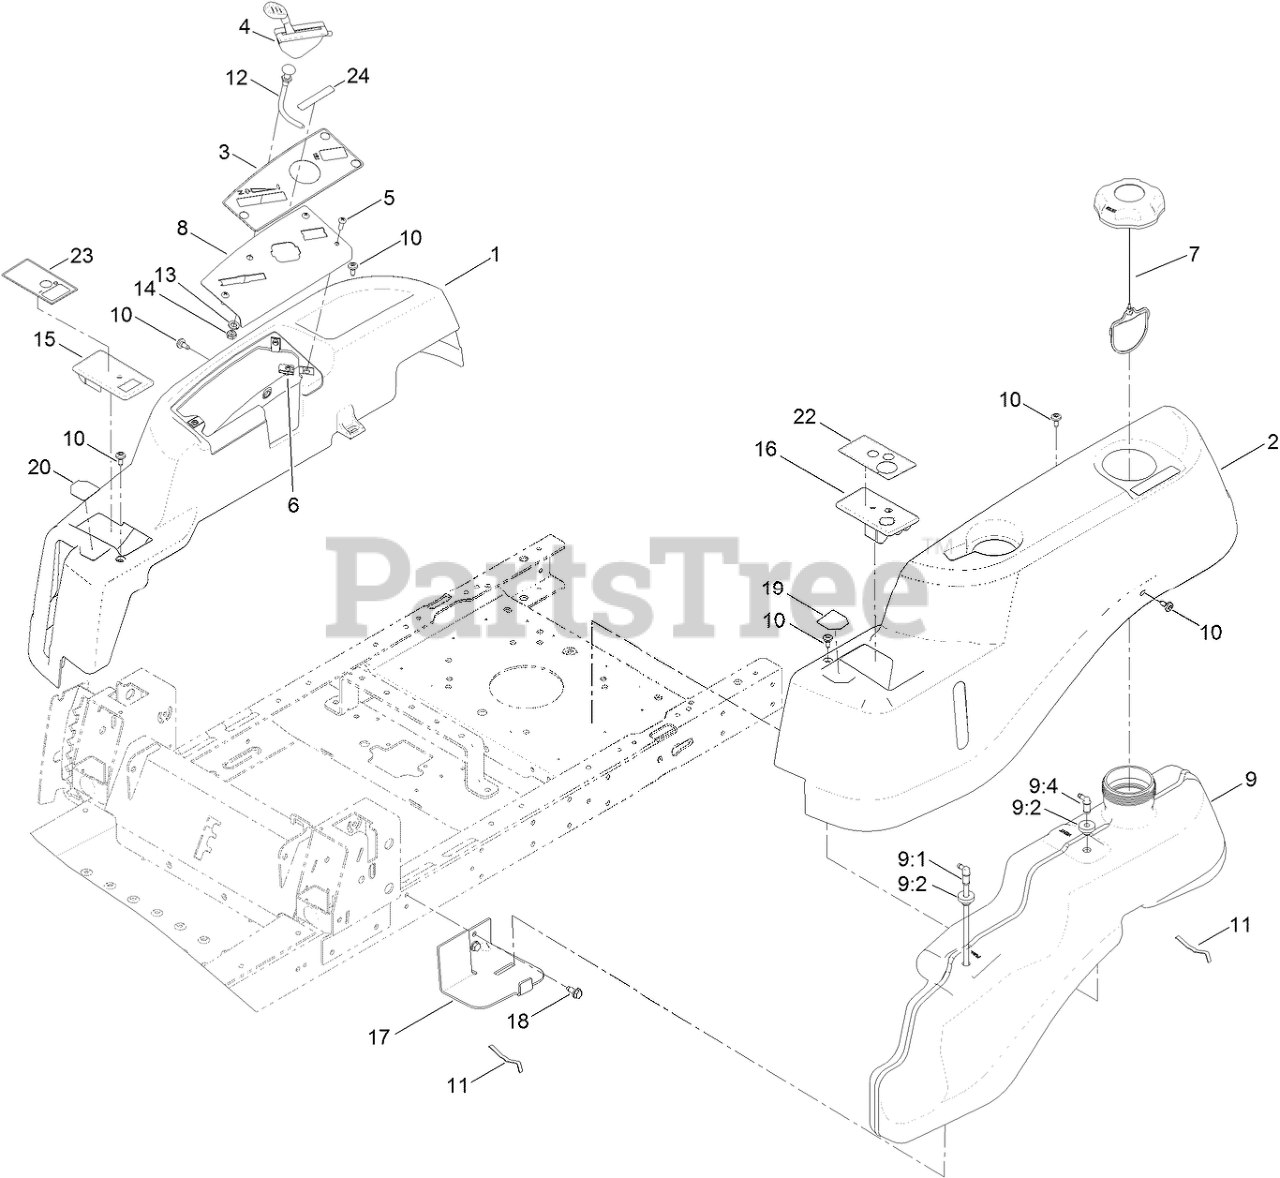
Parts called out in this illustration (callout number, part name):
1	POD-RH
2	POD-LH
3	DECAL-PANEL, CONTROL
4	CABLE-THROTTLE
5	SCREW-PRH
7	CAP-FUEL, RATCHETING
8	PLATE-CONTROL
9	FUEL TANK ASM
9:1	CONNECTOR-ELBOW, 90 DEG
9:2	BUSHING
9:4	FITTING-PLASTIC
10	SCREW-SHOULDER
11	SPRING
12	CABLE-CHOKE
13	WASHER-LOCK
14	NUT-HJ
15	COVER-RH
16	COVER-LH
17	SUPPORT-TANK, FRONT
18	SCREW-HWHTF
19	DECAL-NMIR
20	DECAL-CONTROL, PEDAL
22	DECAL-KEYCHOICE
23	DECAL-BRAKE, PARKING
24	DECAL-SHUTDOWN
